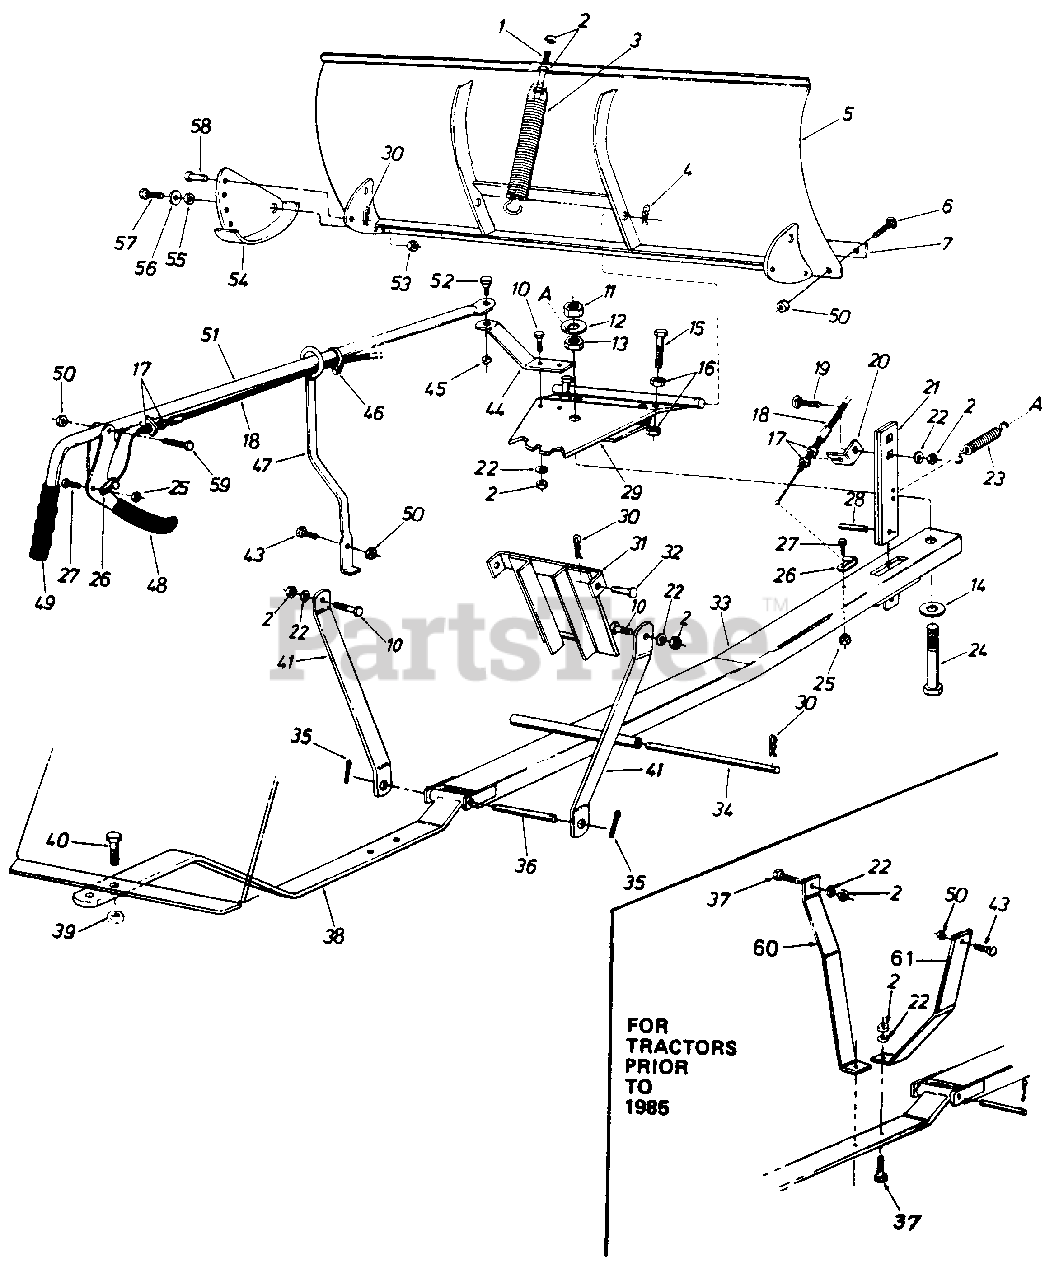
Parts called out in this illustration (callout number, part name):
1	Hex Scr. 3/8-16 x 4.50" Lg.
2	Hex Nut 3/8-16 Thd.
3	Blade Adjustment Spring
4	Hairpin Clip 5/32" Dia.
5	48" Blade Ass'y.
6	Carriage Bolt 5/16-18 x .75" Lg.
7	Wear Plate 48"
10	Hex Scr. 3/8-16 x 1.00" Lg.
11	Hex L.-Nut 3/4-10 Thd.
12	Fl.-Wash. .810" I.D. x 2.00" O.D.
13	Hex Jam Nut 3/4-10 Thd.
14	Fl.-Wash. .810" I.D. x 2.00" O.D.
15	Hex Scr. 1/2-13 x 2.00" Lg.
16	Hex Nut 1/2-13 Thd.
17	Hex Jam Nut 5/16- 24 Thd.
18	Control Cable Ass'y.
19	Carriage Bolt 3/8-16 x 1.25" Lg.
20	Cable Guide Bracket
21	Angle - Lock Bar
22	L.-Wash. 3/8" I.D.
23	Angle Lock Spring
24	Hex Scr. 3/4-10 x 4.00" Lg. Special
25	Hex L.-Nut 1/4-20 Thd.
26	Clevis Lanyard Fitting
27	Hex Scr. 114-20 x .75" Lg.
28	Roll Pin 1/4" Dia. x 1.00" Lg.
29	Pivot Plate Ass'y.
30	Hairpin Clip 3/32" Dia.
31	Guide Bracket Ass'y.
32	Clevis Pin 1 2" Dia. x 1.00" Lg.
33	Push Bar Ass'y.
34	Lift Shaft
35	Cotter Pin 5/32" Dia. x 1.00" Lg.
36	Pivot Shaft
37	Hex Scr. 3/8-16 x 1.25" Lg.
38	Hanger Bracket Ass'y.
39	Hex L.-Nut 5/8-11 Thd
40	Hex Scr. 5/8-11 x 1.50" Lg.
41	Hanger Link
43	Hex Bolt 5/16-18 x 1.00" Lg.
44	Blade Pivot Bracket
45	Hex L.-Nut 3/8-16 Thd.
46	Nylon Cable Tie
47	Tube Guide Ass'y.
48	Clutch Grip Ass'y.
49	Grip-3/4" Handle
50	Hex L-Nut 5/16-18 Thd.
51	Tube Handle Ass'y.
52	Shld. Scr.-Special 3/8-16 Thd.
53	Hex L.-Nut 3/8-16 Thd.
54	Skid Assembly
55	Spacer
56	Fl.-Wash. .385" I.D. x 1.00" O.D.
57	Hex Scr. 3/8-16 x4.75" Lg.
58	Clevis Pin 5/16" Dia. x .75" Lg.
59	Hex Scr. 5/16-18 x 1.50" Lg.
60	Mounting Brkt.-L.H.
61	Mounting Brkt.-R.H.
